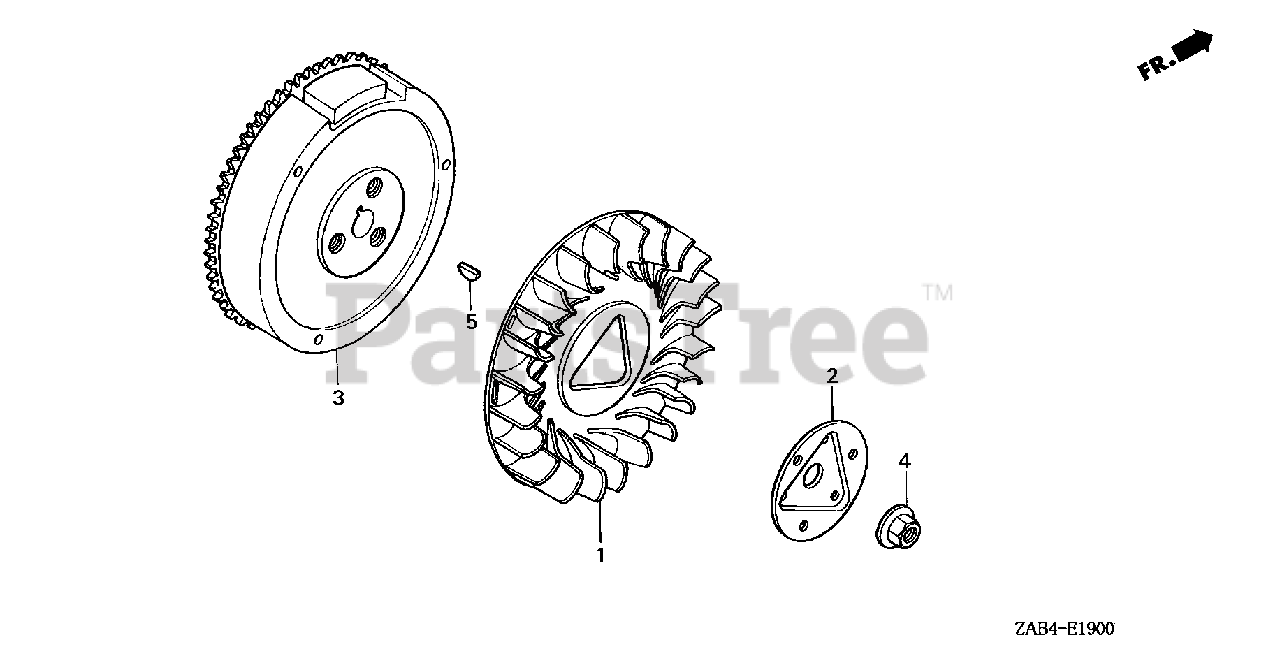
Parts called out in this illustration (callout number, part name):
1	FAN, COOLING
2	PLATE, COOLING FAN SETTING
3	FLYWHEEL (4POLE)
4	NUT, SPECIAL (16MM) (1)
5	KEY, SPECIAL WOODRUFF (25X18)
